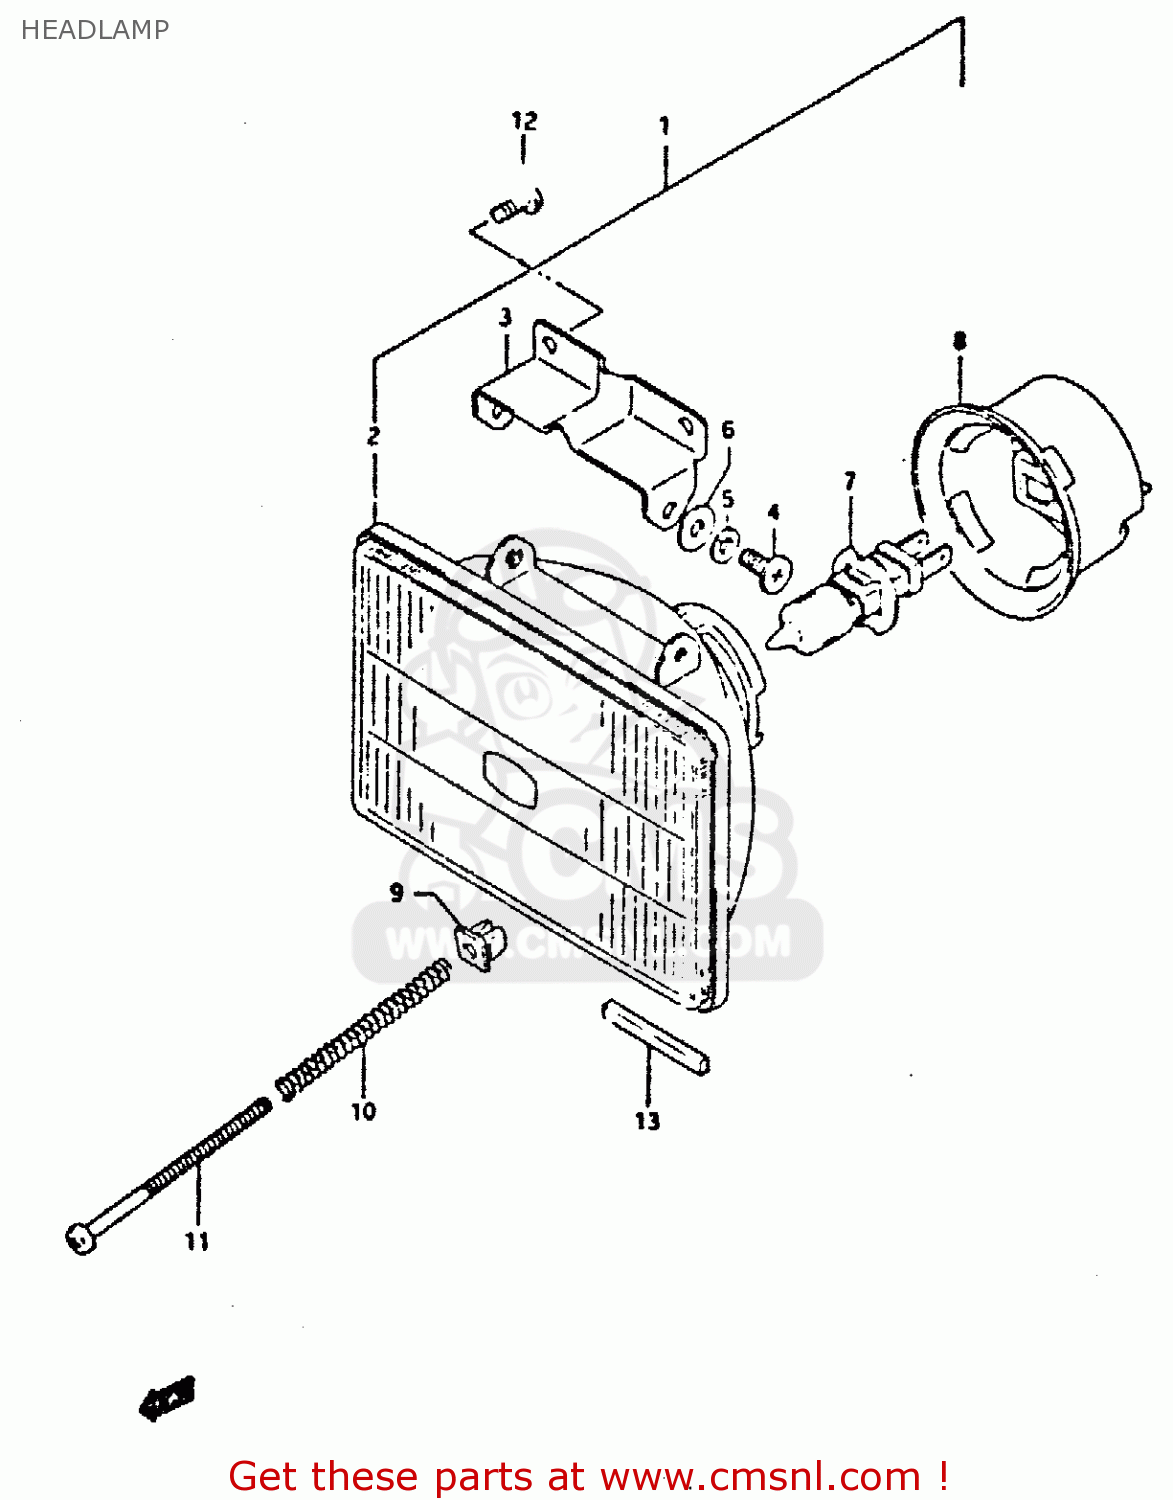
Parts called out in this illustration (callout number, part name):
1	HEADLAMP ASSY
2	UNIT,LAMP
3	BRACKET,LAMP
4	SCREW
5	WASHER,LOCK
6	WASHER
7	BULB(12V55W)
8	COVER,SOCKET
9	NUT,ADJUSTING
10	SPRING,HEAD LAMP ADJUSTER
11	SCREW
12	SCREW
13	PROTECTOR,BATTERY
